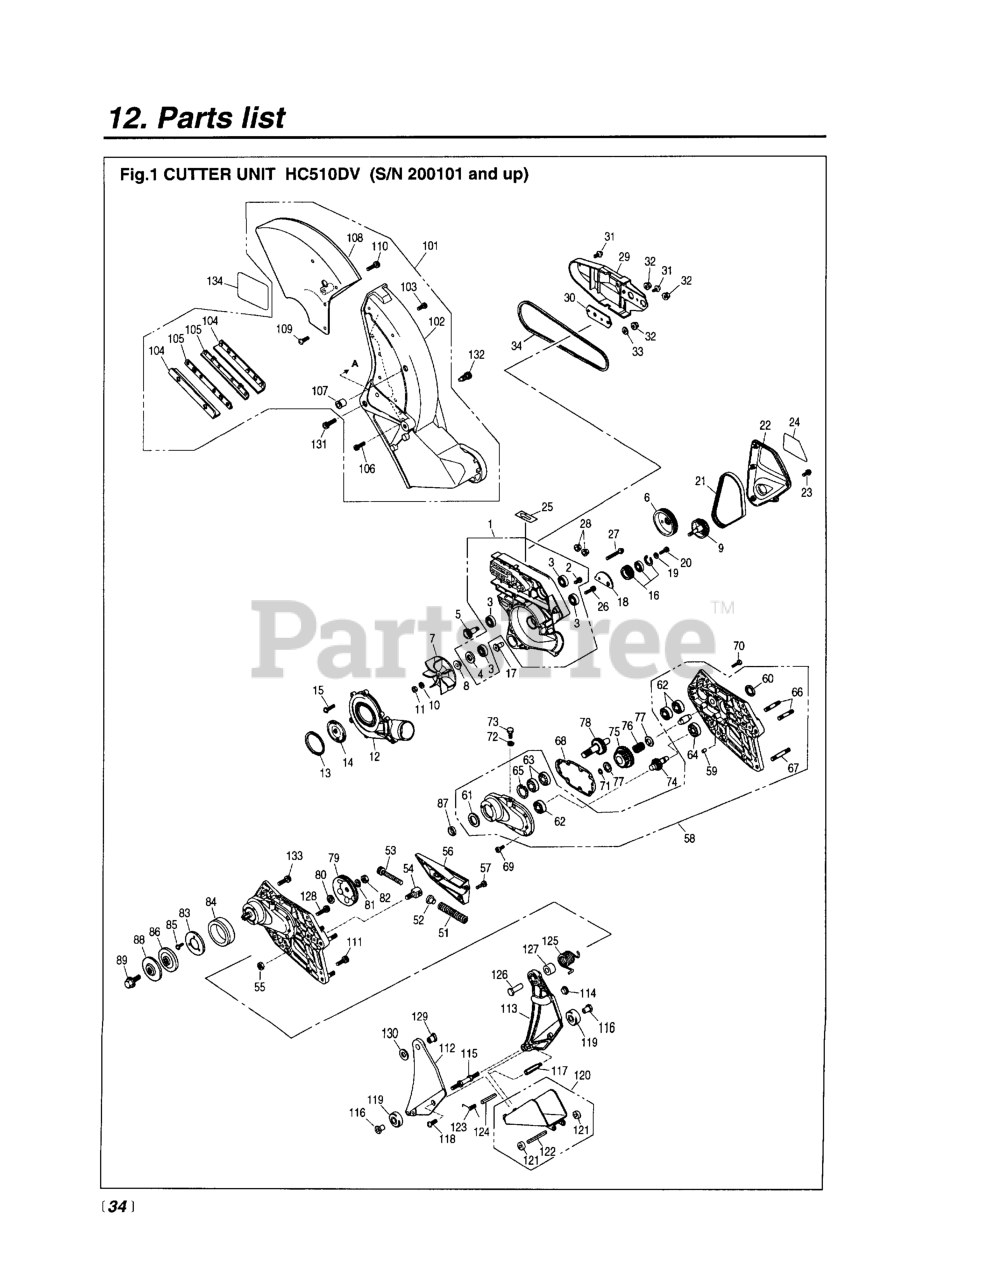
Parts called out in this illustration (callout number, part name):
1	CASE COMP
3	BEARING
4	SEAL, OIL
5	SHAFT, INLET
9	SHAFT COMP.
10	WASHER, M8 x 2.3 (RPLS -20823)
11	NUT (RPLS -43230)
12	COVER, FAN
16	IDLER PULLEY COMP.
17	SHAFT, IDLER
18	CAM PLATE
19	WASHER, M6 X 2.3
22	COVER, BELT
23	SCREW (REPLACES 2616-24320)
28	NUT
29	COVER, PULLEY
31	SCREW
32	NUT
33	WASHER, M8 x 2.3 (RPLS -20823)
54	GUIDE NUT
55	NUT (RPLS -43230)
56	COVER, SPRING
57	SCREW (REPLACES 2616-24320)
58	GEARCASE COMP.
59	PIN, DOWELL
62	BEARING
65	RING, SNAP, M32 x 1.2
74	SHAFT COMP.
75	GEAR COMP.
78	SHAFT COMP.
81	WASHER, M8 x 20
82	NUT (RPLS -43230)
83	PLATE, END
84	END RING
101	COVER ASSY.
102	BLADE COVER
108	COVER, UPPER
109	SCREW (REPLACES 2616-24320)
112	FRONT GUIDE (R)
113	FRONT GUIDE (L)
115	JOINT BOLT
117	JOINT BOLT
118	SCREW
120	SLIDE GUIDE COMP
122	SPRING PIN
123	RETURN SPRING
124	SPRING PIN
125	RETURN SPRING
132	STOPPER BOLT
134	LABEL, CAUTIION
